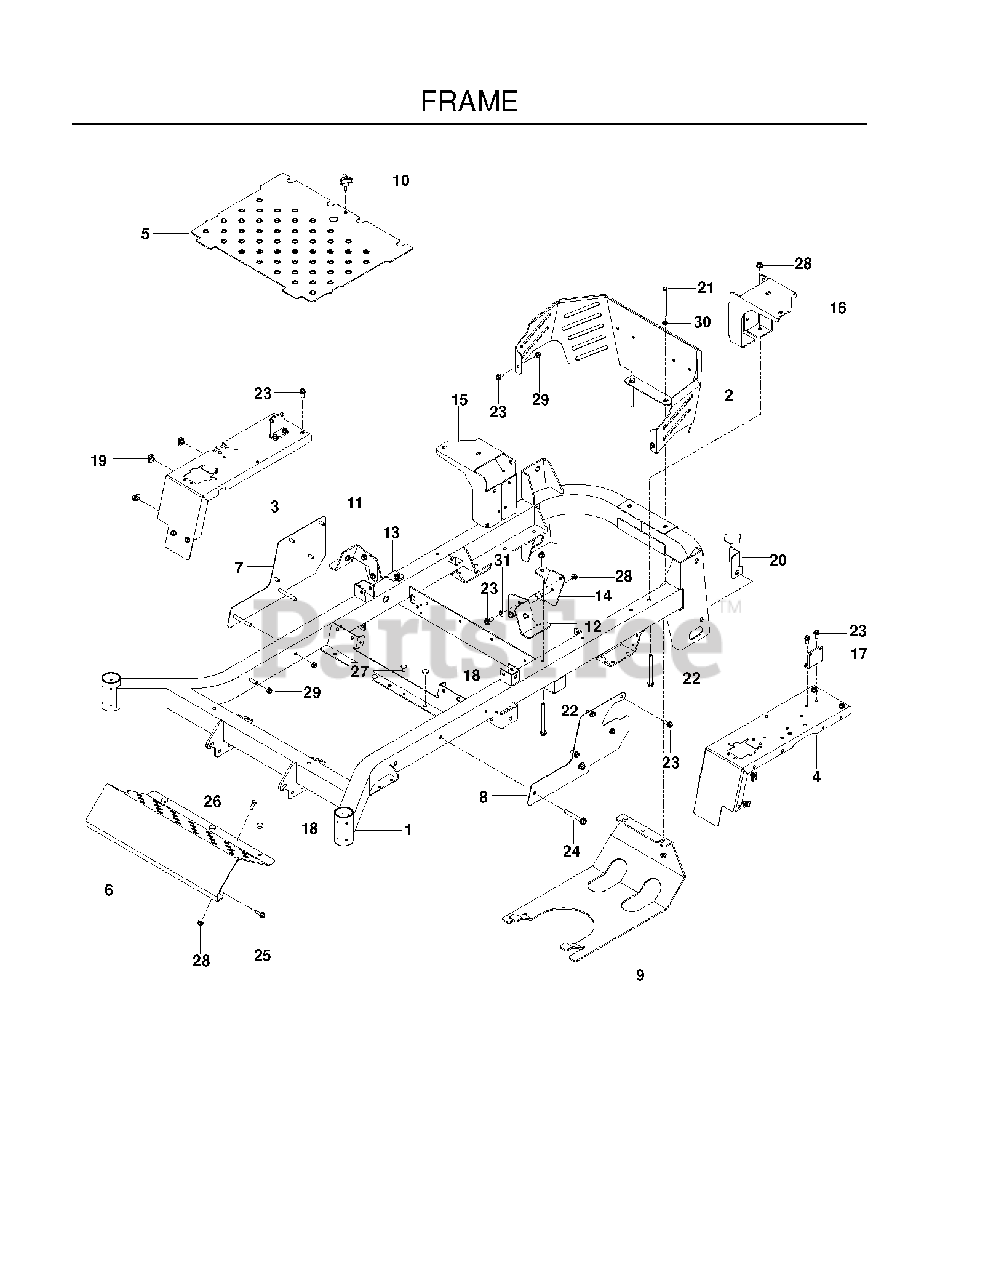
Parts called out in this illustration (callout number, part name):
3	PANEL, FILLER RT, BLUE
4	PANEL, FILLER LT, BLUE
5	FLOOR PAN W/DECALS
6	PLATE, FOOT REST - RAM DK BLUE
7	SIDE, RT, BL
8	SIDE, LT, BL
9	GUARD, SKID, BLUE
10	KNOB W/STUD
11	MOUNT, TANK, RT-BLK
12	MOUNT, TANK, LT-BLK
18	HHFS 5/16-18 X 3 3/4
19	U-CLIP 5/16-18 NUT RETAINER
20	HHFS 3/8-16 X 2 3/4
21	HCS 5/16C X 4
22	RHSNB 5/16C X 1
23	HHFS 5/16-18 X 3/4
24	5/16-18 NYLOC FLANGE NUT
25	BLT 5/16-18 X 1 THRD FORM ZD
26	FLAT WASHER 5/16 SAE
27	BOLT 5/16C X 3/4" CARRIAGE
28	GROMMET, BUMPER
29	NUT HEX 3/8-16 NYLON, THIN
31	WASH 5/16 DISC SPRING ZD
